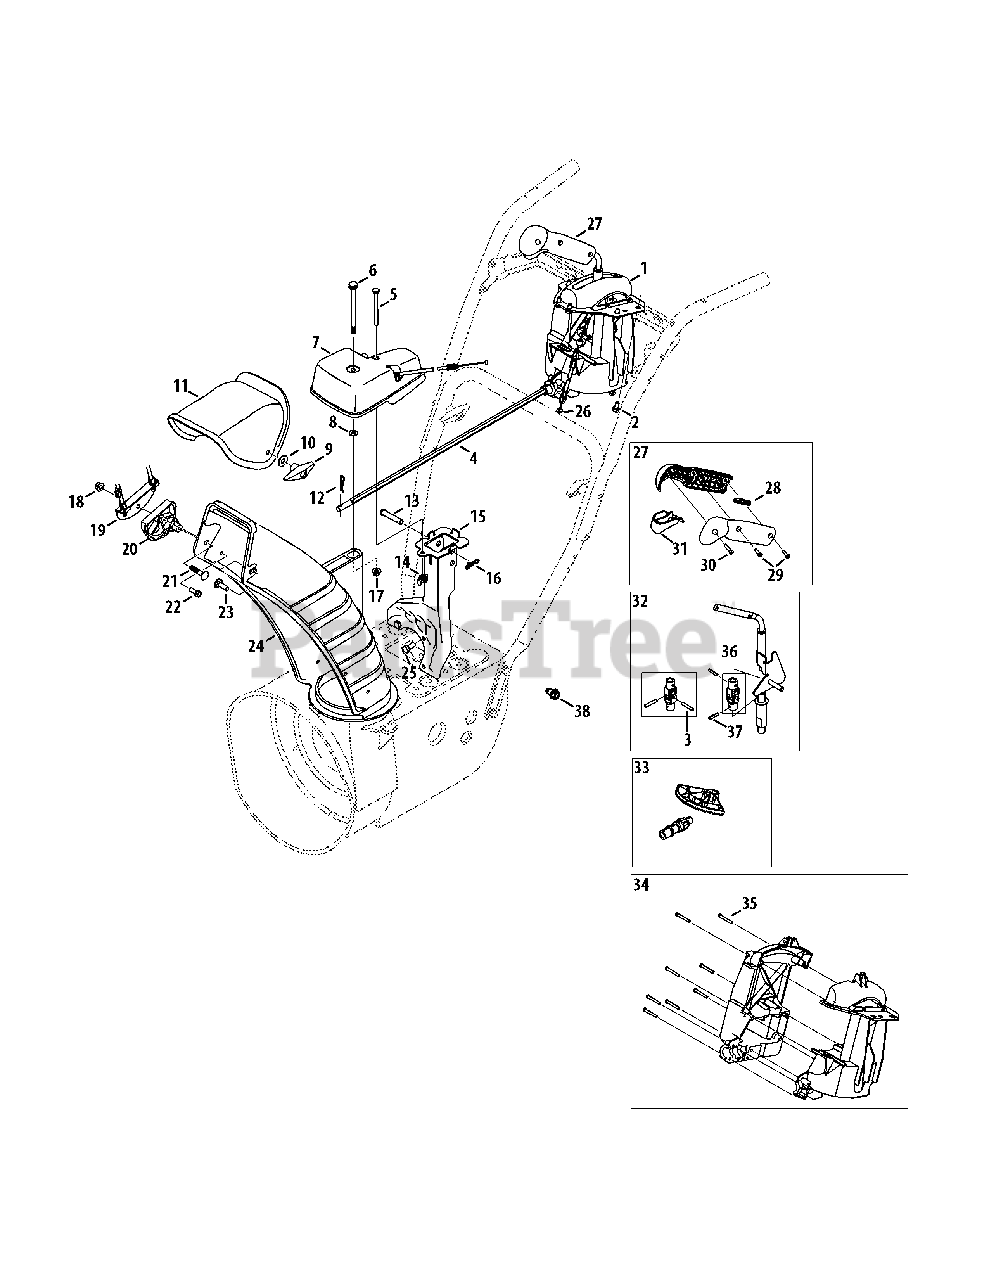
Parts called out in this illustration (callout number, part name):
1	4-Way Chute Control™ Assembly
2	Hi-Lo Screw, 1/4-15 x 0.5
3	Roll Pin
4	Chute Rod
5	Hex Screw, 1/4-20 x 3.00
6	Flange Shoulder Screw
7	4-Way Chute Gearbox Assembly
7	Screw-Hl #12-16 .7
7	Shaft-Worm Drv Hex
7	Nut-Hex Ins-L
7	Gear-14T Helical
7	Gear-Worm
7	Cover-Chute Grbx
7	Spring-Torsion
7	Washer-Fl
7	Bolt-Shoulder
7	Flange Bearing
7	Cable-Chute Lock
7	Bracket-Rotate Grb
7	Pawl-Chute Lock
7	Brg-Hex Flange
8	Flat Washer, .25 x .630 x .0515
9	Wing Knob
10	Flat Washer, .349 x .879 x .063
11	Upper Chute
12	Cotter Pin
13	Clevis Pin
14	Wing Nut, 1/4-20
15	Chute Support Bracket
16	Bow Tie Cotter Pin
17	Flange Lock Nut, 1/4-20
18	Flange Lock Nut, 5/16-18
19	Cable Bracket
20	Chute Tilt Cable Guide
21	Carriage Bolt, 5/16-18 x 1.50
22	Hi-Lo Screw, 1/4-15 x .75
23	Carriage Bolt, 5/16-18 x 1.0
24	Lower Chute
25	Hex Screw, 5/16-24 x .750
26	4-Way Cable
27	Handle Assembly
28	Handle Plunger
29	Screw, Mach., #8-32 x .750
30	Screw, #8 x 1.00
31	Handle Lever
32	Shift Assembly
33	Gear Set Assembly
34	Handle Housing Assembly
35	Screw, #8-18 x 1.250
36	Joint Block Assembly
38	Screw (For ground wire)
